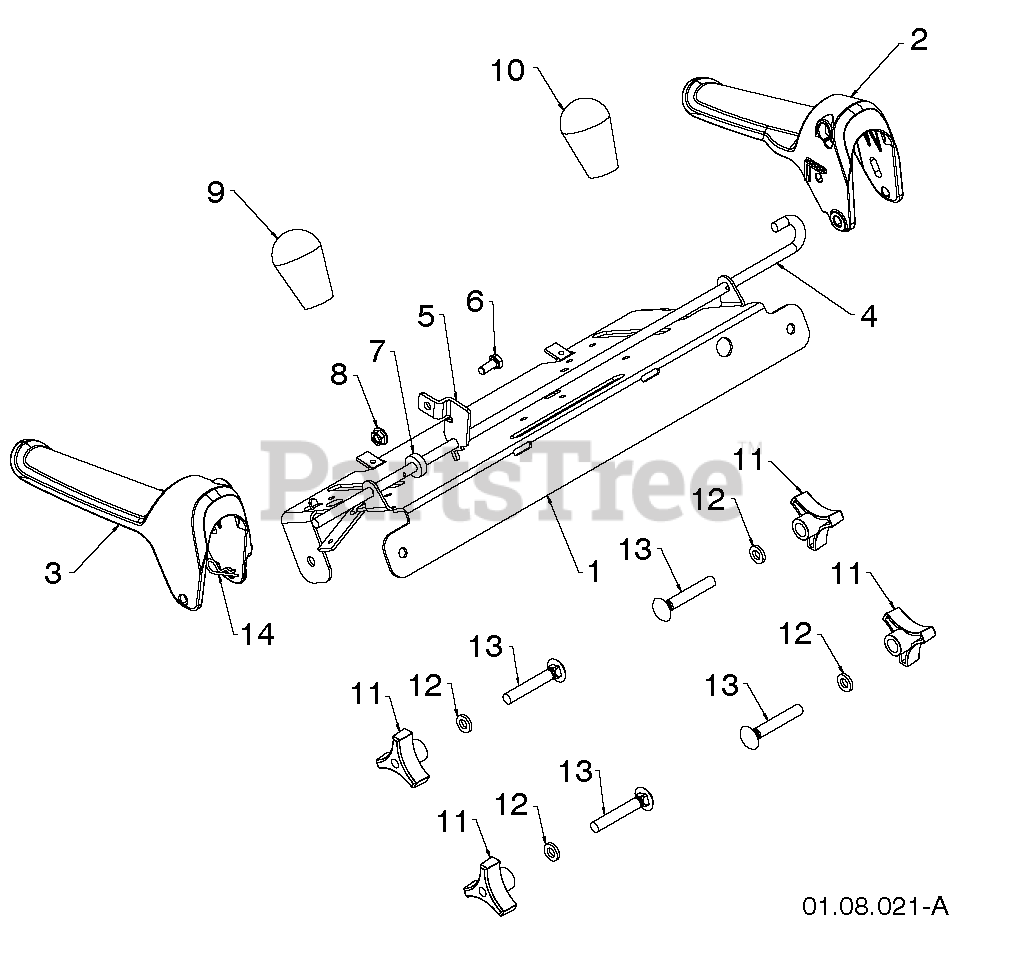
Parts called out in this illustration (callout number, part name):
1	PANEL.CONTROL.SNOW.BLACK
2	LEVER.CONTROL.LH.PL.BLACK
3	LEVER.CONTROL.RH.PL.BLACK
4	BAIL.CONTROL.INTERLOCK.SNOW
5	ARM.IMPELLER.ROD.
6	BOLT
7	SPACER.CONTROL.LEVER
9	RED KNOB SHIFTER
10	KNOB LEVER, BLACK
11	KNOB.HANDLE.3/8.TRI-POINT.BLAC
13	BOLT 3/8-16 X 2-1/4
14	SPRING RETAINER
